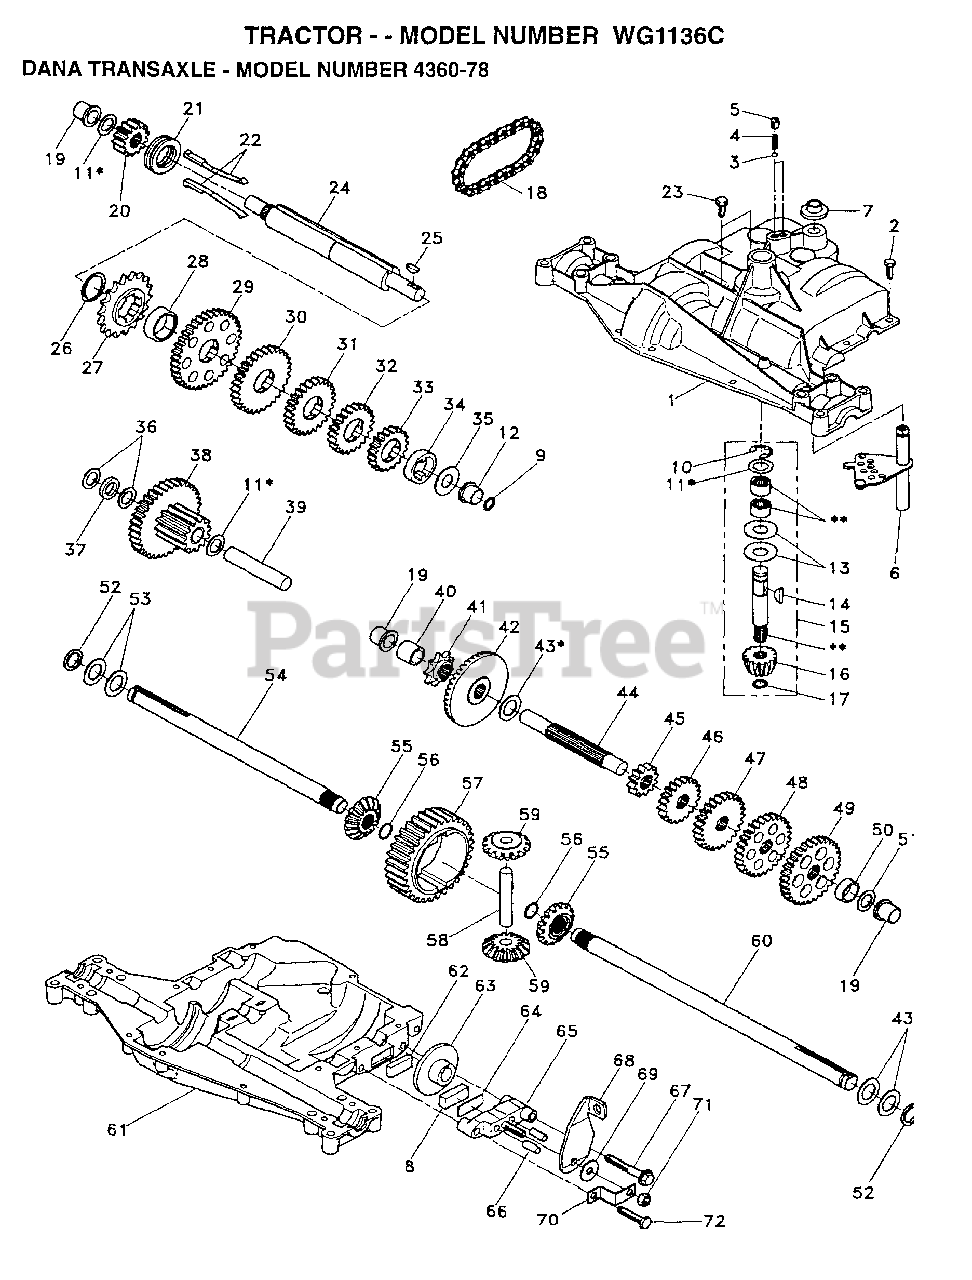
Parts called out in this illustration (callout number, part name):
1	HOUSING UPPER TRN
4	"SPRING, DETENT LT"
5	"SCREW, SET LT"
6	KIT SHIFTER ASM
7	SHIFTER BOOT
8	PUCK T
9	SEAL OIL DANA5416
11	ASM KIT SHIM 4689
13	WASHER T
14	KEY WOODRUFF-DANA
15	AS KIT INPUT SHFT
16	PINION 14T T
17	"RING,RETAINING LT"
18	"CHAIN,24 PTCH LT"
19	BEARING.FLNG.5510
20	GEAR SPUR 14 TTH
21	COLLAR CLUTCH
22	ASM KIT CLTCH KEY
23	SCREW TAP W/SEAL
24	SHAFT INTERM DANA
25	WOODRUFF KEY
26	"RING,RETAINING LT"
27	SPROCKET 18T T
28	SPACER YT
29	GEAR SPUR 37 TTH
31	GEAR 25T LT
32	GEAR SPUR 22 TT
33	SPUR GEAR 19T
34	SPACER
35	"WASHER, PLAIN LT"
36	WASHER 025
37	SPACER
38	ASSM GEAR COMB
39	SHAFT IDLER
40	SPACER T
41	SPROCKET 9T LT
43	ASM KIT SHIM
44	SHAFT T
45	GEAR SPUR 12 TTH
47	"GEAR, SPUR 25T LT"
48	GEAR 28T T
49	"GEAR, SPUR 31T LT"
51	WASHER 060
52	NEOPRENE WASHER
53	WASHER 031
55	GEAR 15T T
56	"RING,RETAINING LT"
58	SHAFT T
59	GEAR 1ST T
61	HOUSING LOWER TNS
62	PUCK T
63	BRAKE DISC. T
64	SPACER LT
66	PIN T
69	WASHER LT
71	NUT.LOCK.5/16-24
72	"SCREW, TAPPING LT"
